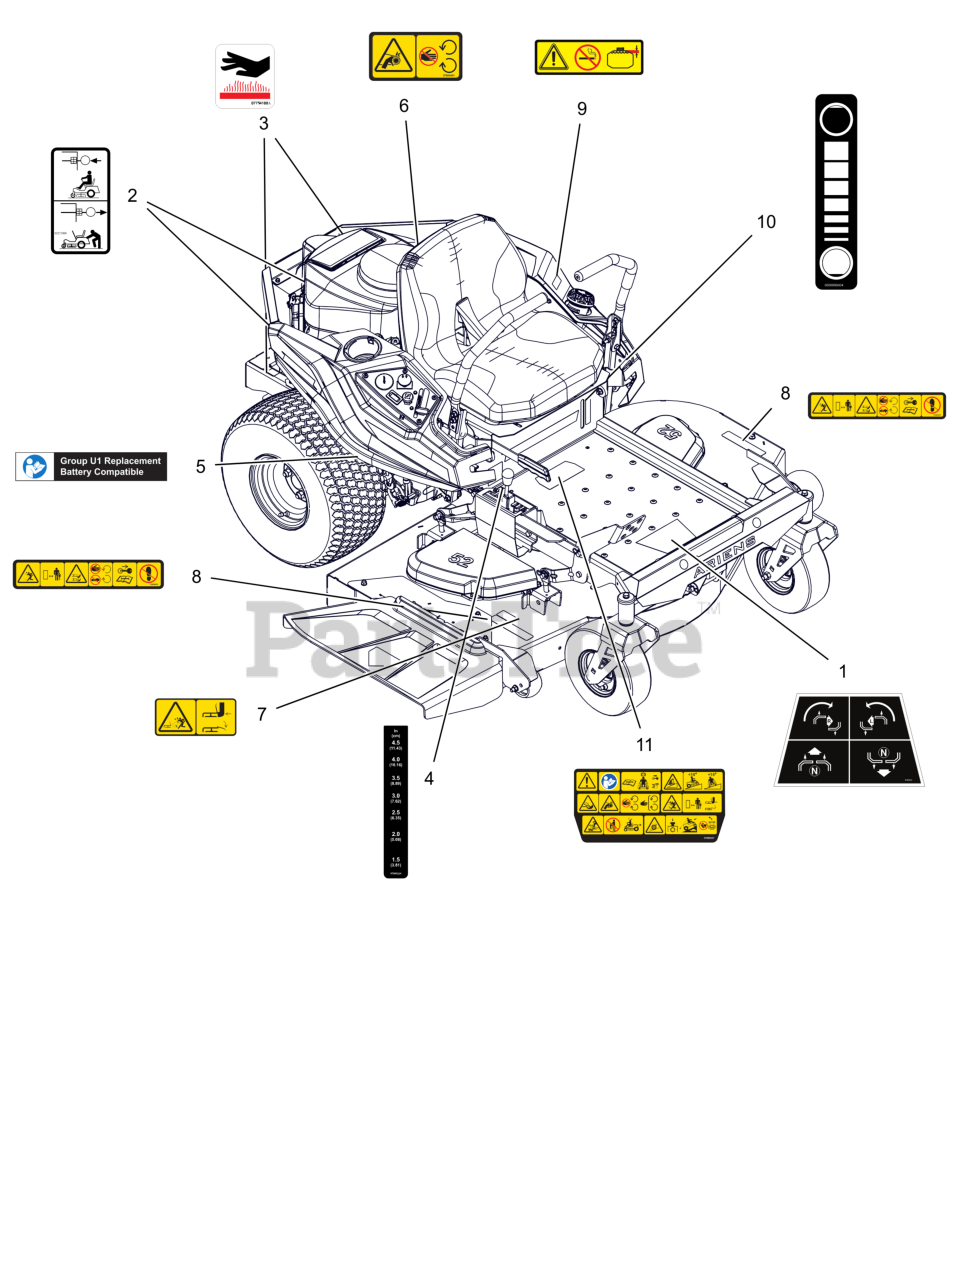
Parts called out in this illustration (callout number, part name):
1	DECAL, STEERING
2	DECAL, TRANSMISSION DISCONNECT
3	DECAL, HOT SURFACE
4	DECAL, HEIGHT OF CUT
5	DECAL, U1 BATTERY REPLACEMENT
6	DECAL, SAFETY - GUARDING
7	DECAL, SAFETY - DECK GUARDING
8	DECAL, DECK SAFETY
9	DECAL, FUEL WARNING
10	DECAL, FUEL LEVEL
11	DECAL, MAIN SAFETY
